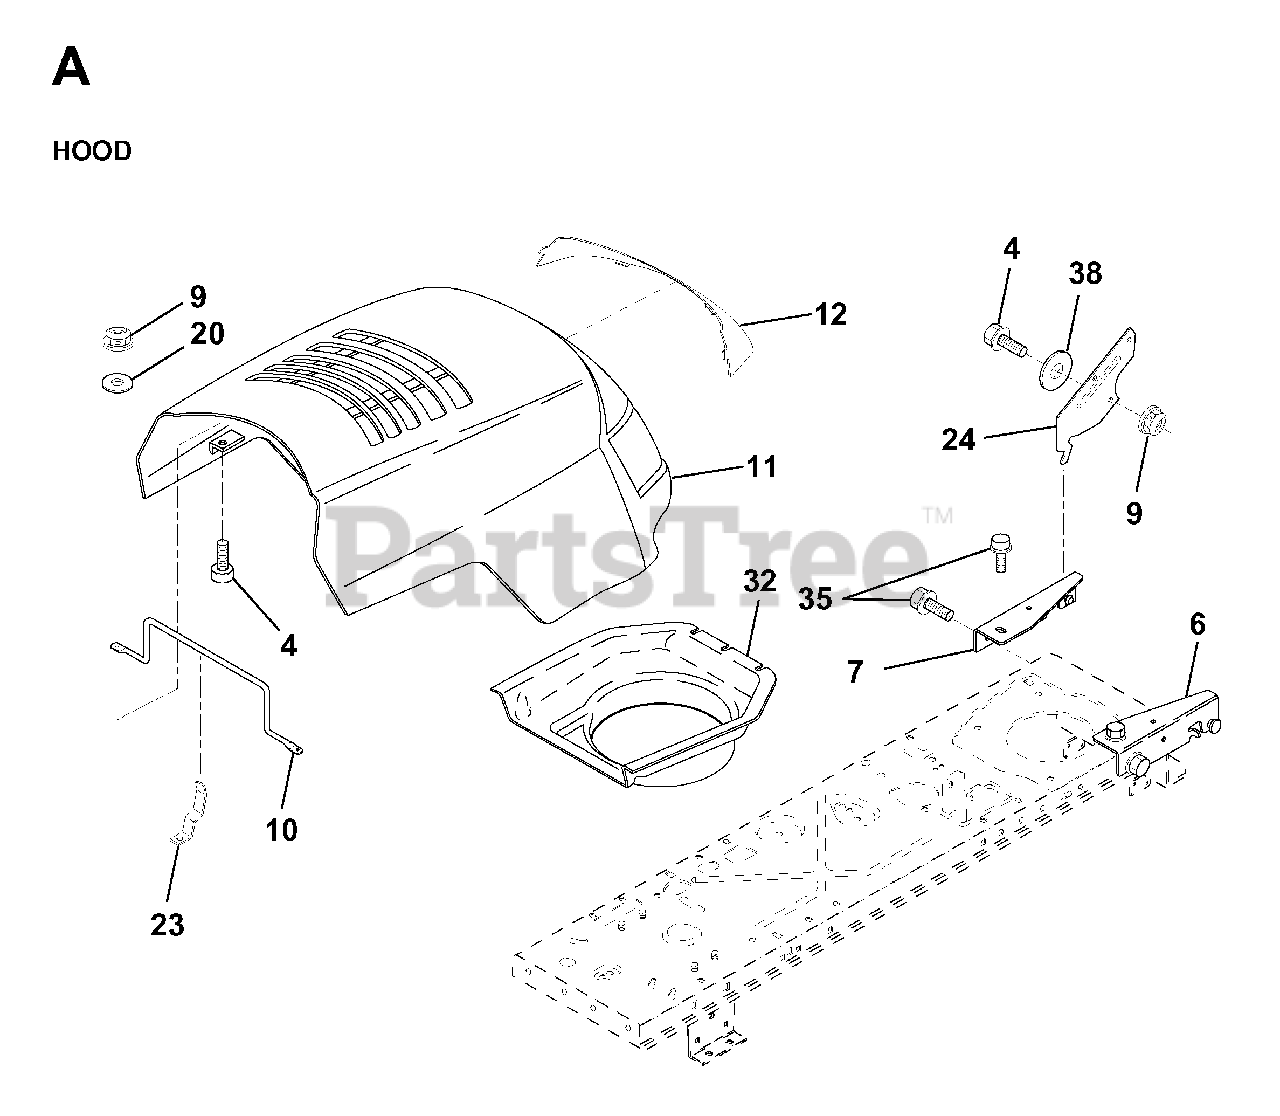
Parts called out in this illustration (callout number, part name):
6	BRACKET ASSY HOOD
7	BRACKET ASSY
9	LOCKNUT
20	WASHER
23	HOOD LATCH
35	SCREW
